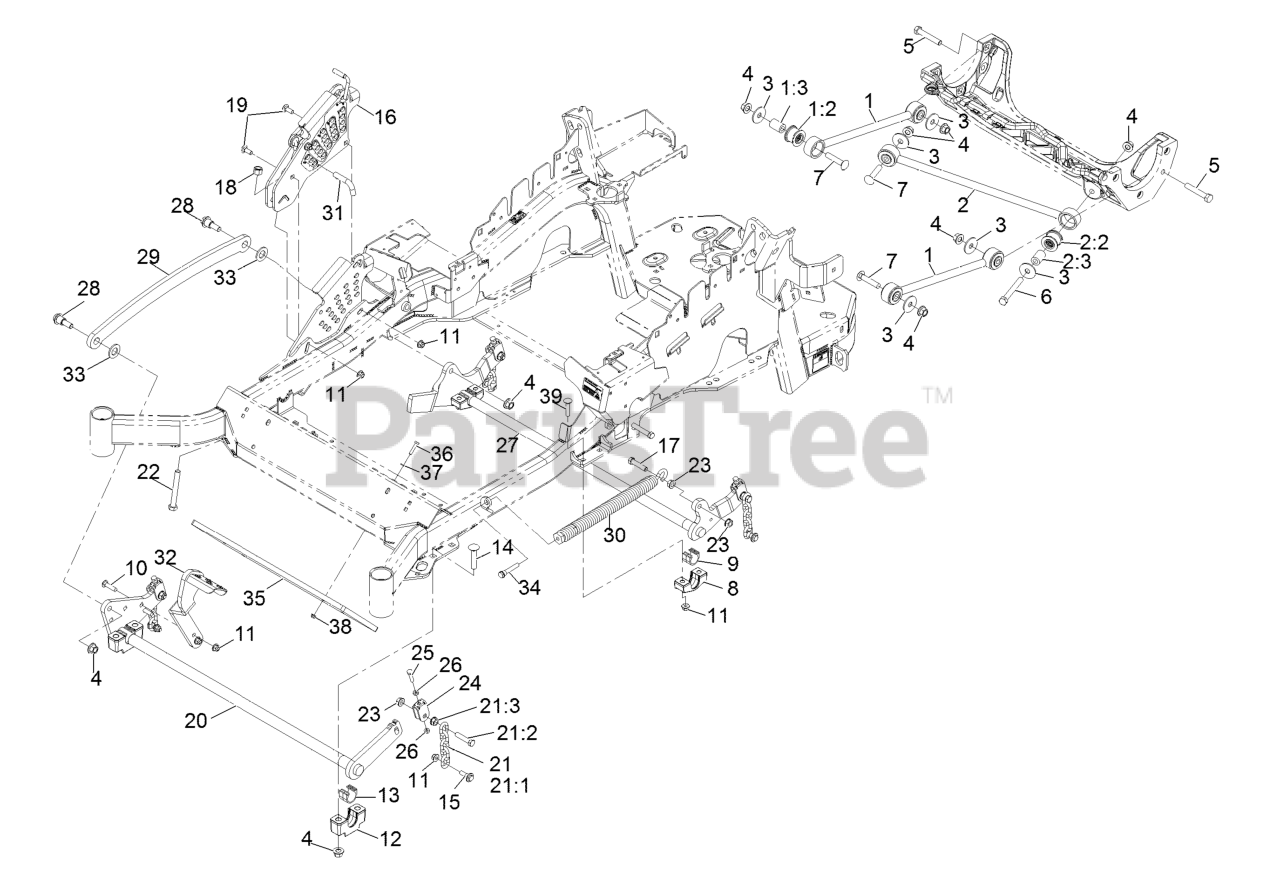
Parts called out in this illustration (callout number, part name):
1	DECK STRUT ASM
1:2	BUSHING-SUSPENSION, RUBBER
2	PANHARD ROD ASM
2:2	BUSHING-SUSPENSION, RUBBER
3	WASHER-THRUST
4	Nut-Lock 1/2-13
5	SCREW-HH
6	SCREW-HH
7	SCREW-CARR
9	BEARING-CROSS SHAFT, REAR
10	SCREW-CARR
11	NUT-HF, NI
12	SUPPORT-CROSS SHAFT, BEARING
13	BEARING-CROSS SHAFT, FRON
14	Bolt-Carriage 1/2-13 X 2 1/2 Spl Neck
15	SCREW-SHOULDER, HHF
16	HOC ASM
17	SCREW-HH
18	NUT-LOCK, NI
19	BOLT-CARR
21	DECK LIFT CHAIN ASM
21:1	CHAIN-LIFT, DECK
21:2	SCREW-HH
22	BOLT-TAP
24	YOKE-ADJUST, DECK
25	SCREW-HH
26	NUT-JAM
27	LIFT-DECK, REAR
28	SCREW-SHOULDER, HHF 1/2-13 X 1.12
29	LINK-LIFT, DECK
30	SPRING-EXTENSION
31	PIN-HOC
32	LEVER-FOOT
33	WASHER-FLAT
34	BOLT-SHOULDER
35	WEIGHT,TOE BOARD
36	SCREW-HH
37	WASHER-FLAT
39	SCREW-CARR
